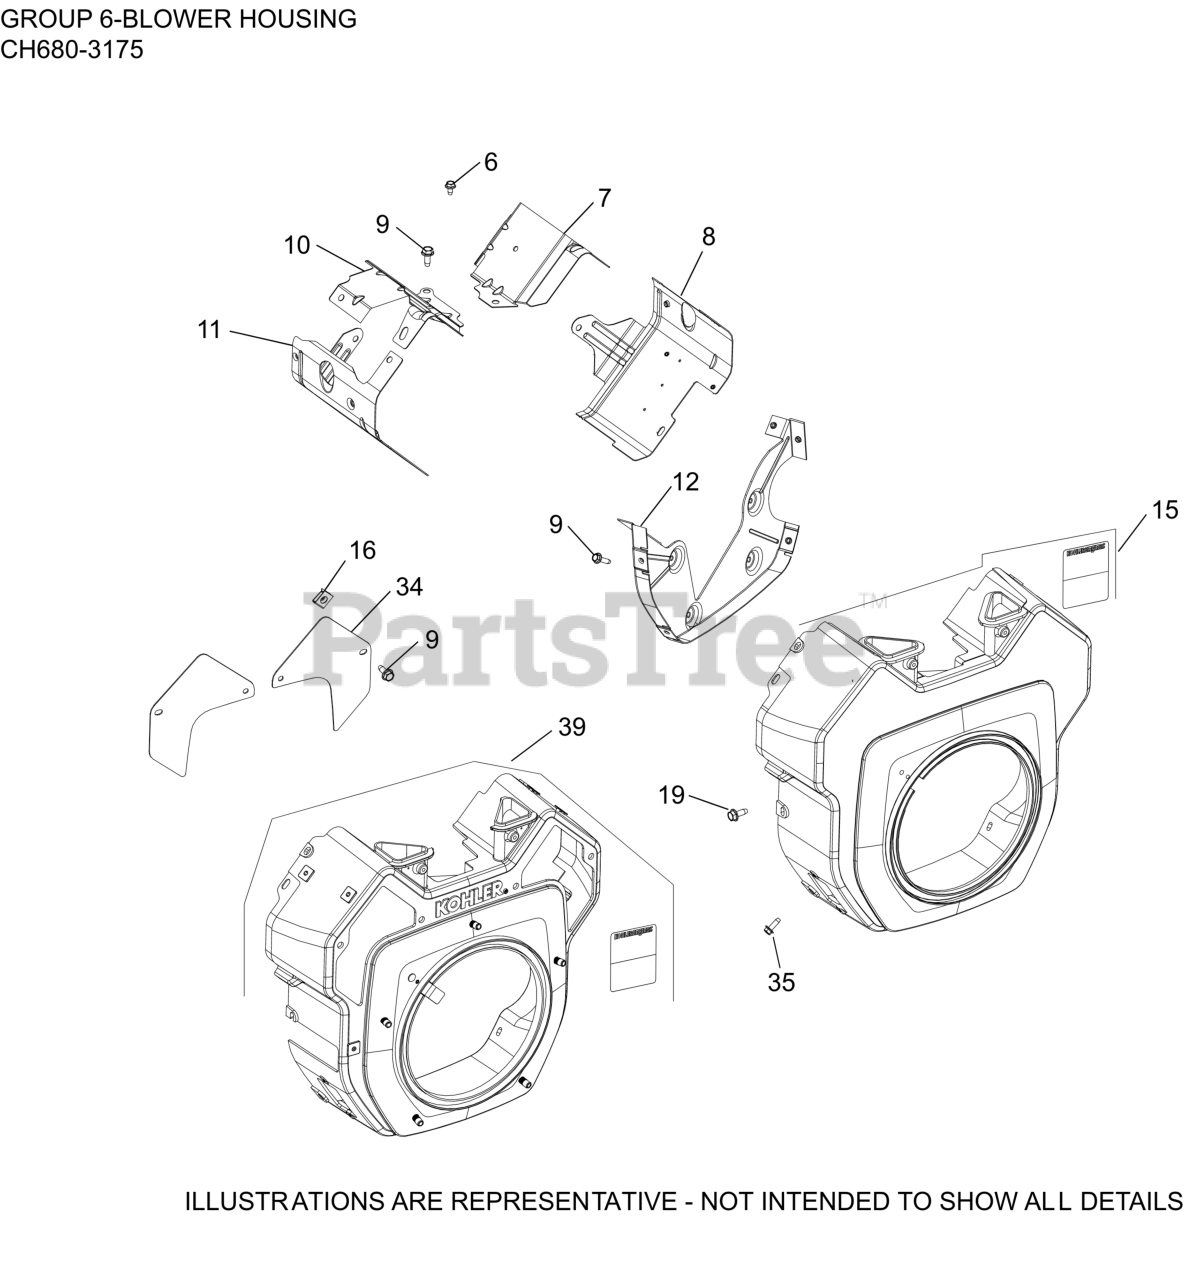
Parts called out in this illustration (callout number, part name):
6	SCREW, THREAD FORMING
7	BAFFLE, VALLEY #1 CYLINDER
8	KIT, CYL BAFFEL #1 SIDE
9	SCREW, THREAD FORMING
10	BAFFLE, VALLEY #2 CYLINDER
11	BAFFLE, LEFT BARREL
12	KIT, BACKING PLATE
15	HOUSING, BLOWER
16	CLIP, BAFFLE MOUNTING
19	SCREW, THREAD FORMING
34	KIT, ACCESS PANEL
35	SCREW, THREAD FORMING
39	KIT, BLOWER HOUSING
